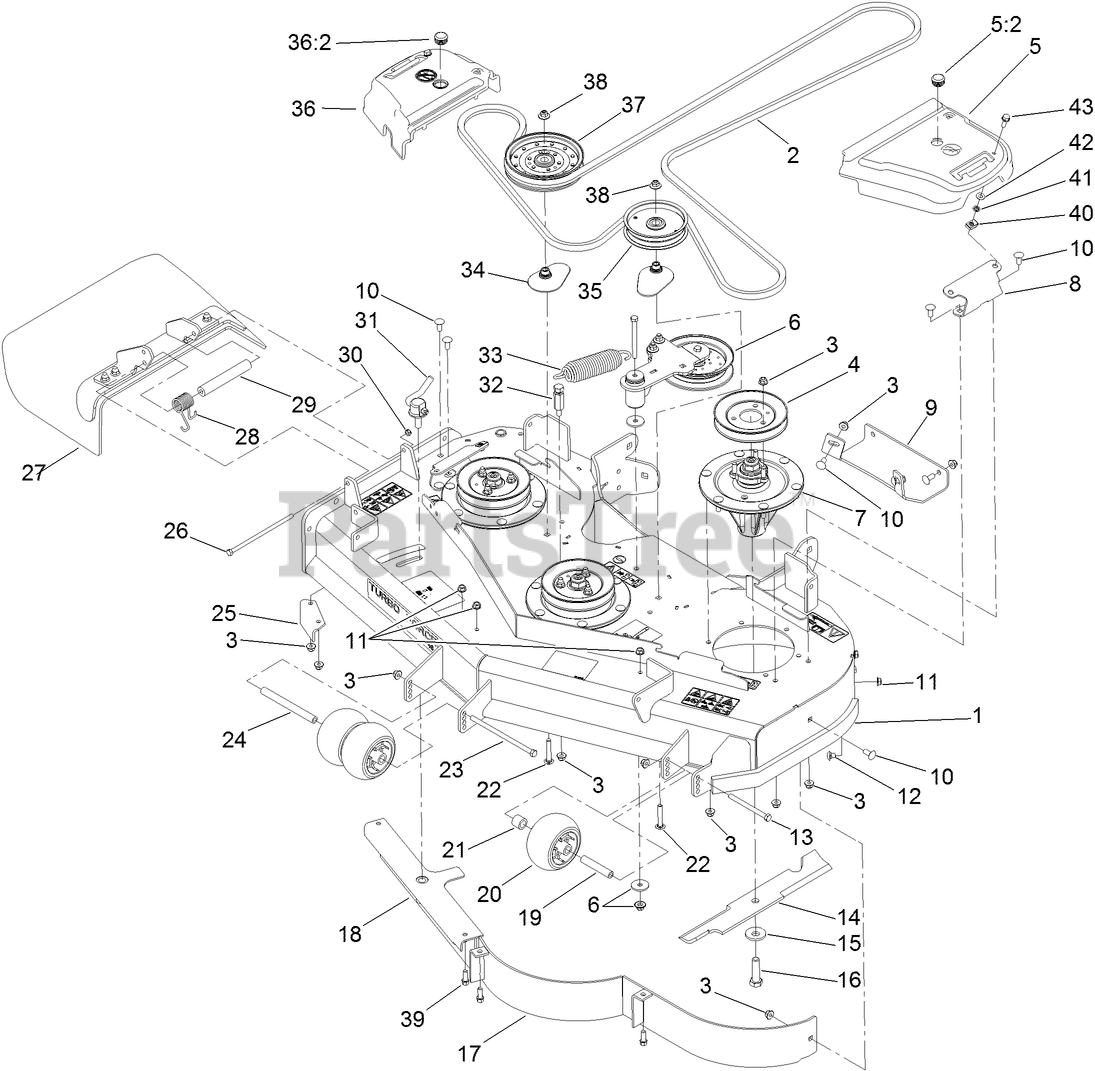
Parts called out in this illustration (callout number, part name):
1	DECK ASM
2	BELT-V
3	NUT-HF, NI
4	PULLEY
5	LH BELT COVER ASM
5:2	PLUG-PLASTIC
6	IDLER ARM ASM
7	SPINDLE ASM
8	BRACKET-COVER, BELT
9	PLATE-SKID
10	SCREW-CARR
11	NUT-HHF, WHIZ
12	SCREW-CARR
13	SCREW-HH
14	BLADE-16.5 INCH (HIGH FLOW)
15	Washer-Blade Bolt, Heavy
16	SCREW-BLADE
18	BAFFLE
19	TUBE-SPANNER
20	ROLLER-SCALP, ANTI
21	TUBE-SPACER
22	BOLT-CARR, SHORT NECK
23	SCREW-HH
24	SPACER-WHEEL
25	BAFFLE-DISCHARGE
26	SCREW-HH
27	RUBBER DEFLECTOR ASM
28	SPRING-TORSION
29	SPACER
30	NUT-LOCK, NI
31	LEVER ASM
32	ANCHOR-SPRING, TALL
33	EXTENSION-SPRING
34	SPACER-PULLEY
35	PULLEY-IDLER
36	RH BELT COVER ASM
36:2	PLUG-PLASTIC
37	PULLEY-IDLER, FLAT
38	NUT-FLANGE, NI
39	SCREW-HWH
40	NUT-U
41	NUT-PUSH
42	WASHER-THRUST
43	SCREW-HHF
